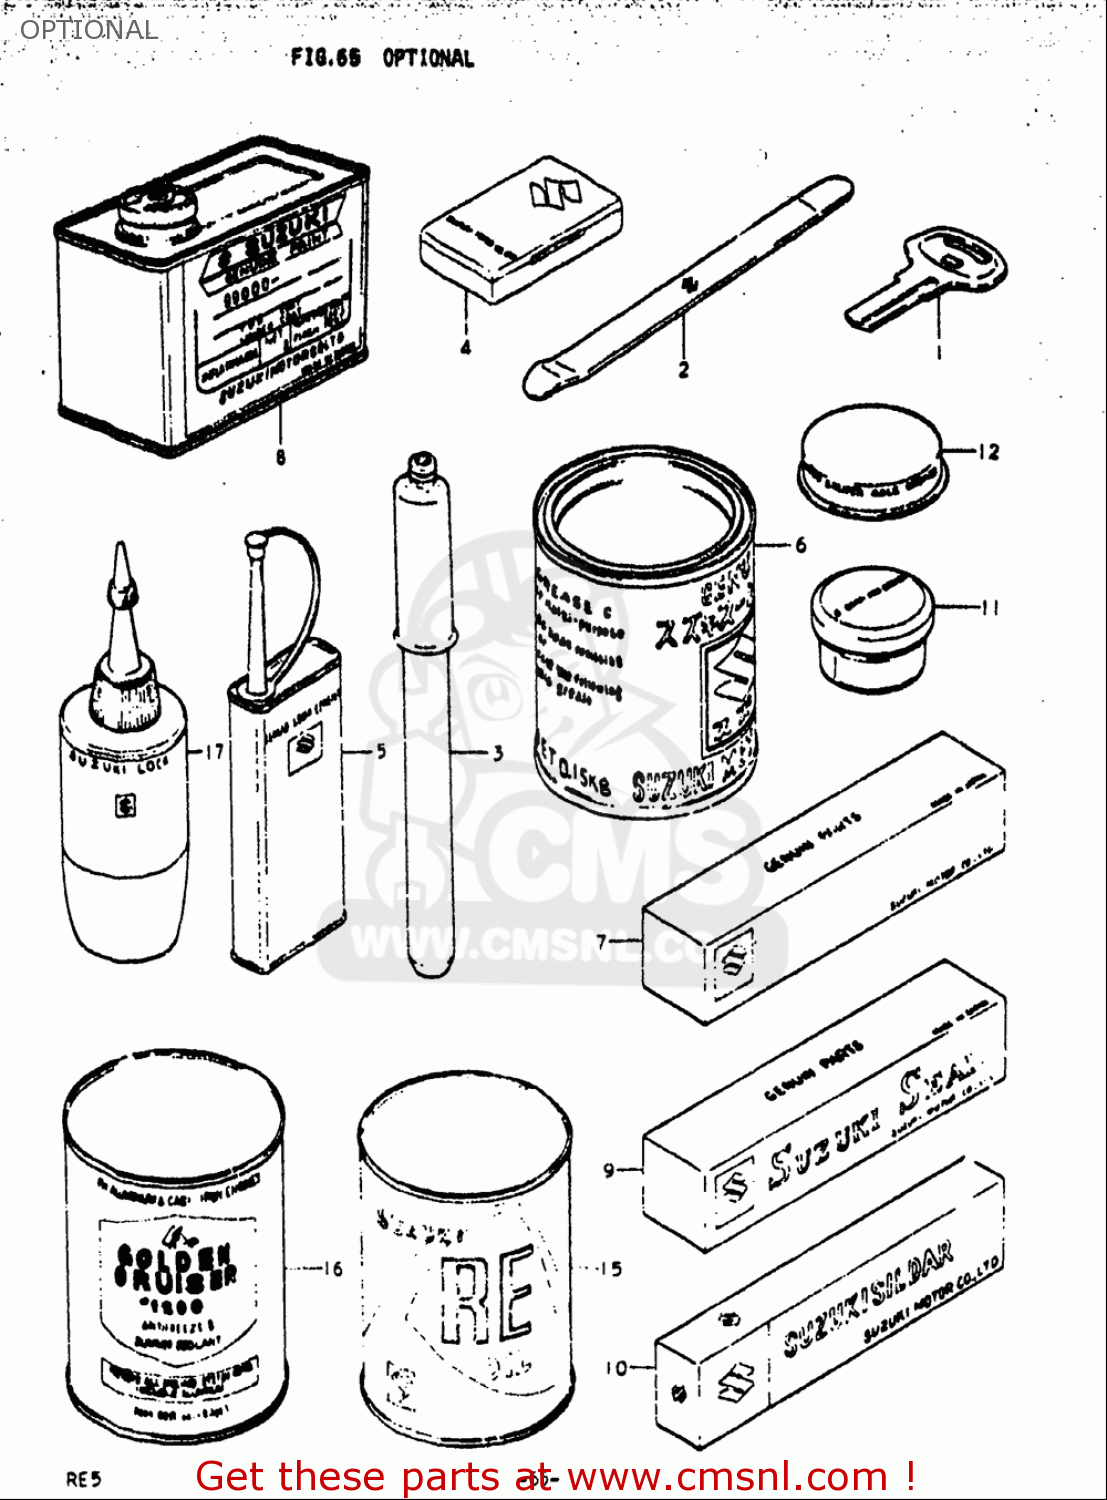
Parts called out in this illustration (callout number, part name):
1	KEY,BLANK
2	LEVER,TIRE
5	THREAD LOCK NO.1401 CLEAR 200G
6	GREASE(C)EP2 LITHIUM 150G
7	BOND 1104
11	GREASE,SILICON 20G
12	GREASE,PBC FOR BRK PAD 20G
15	THREAD LOCK NO.1303B PURPL 50G
